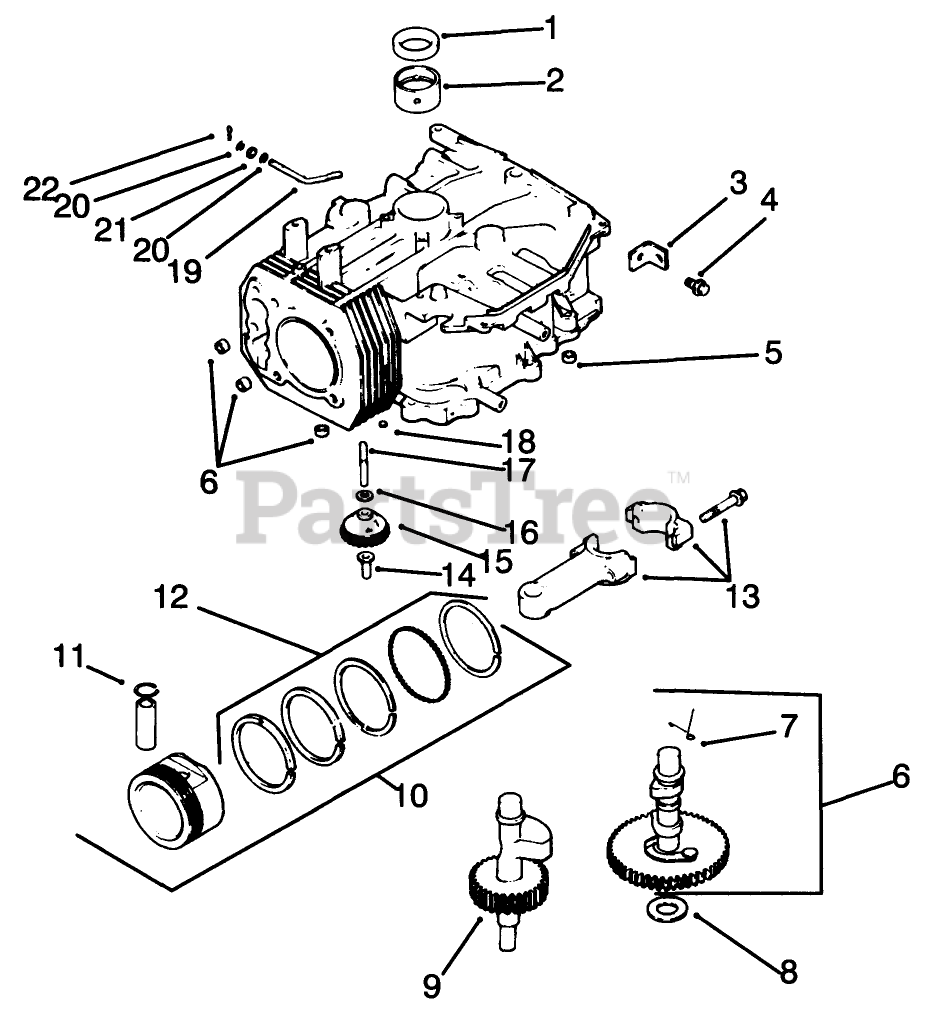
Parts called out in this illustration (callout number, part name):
1	Seal-Crankshaft (Only On: 72042, 72043, 72062, 72063)
2	Bearing-Crankshaft
3	Strap-Lifting (Only On: 72042,72043,72062,72063)
5	Pin-Dowel
6	Camshaft Assembly
7	Spring-Actuating (Only On: 72042,72043,72062,72063)
8	Shim-Camshaft
9	Shaft-Balance
10	Piston W/Ring Set (Std.)
11	Retainer-Piston Pin (Only On: 72042, 72043,72062,72063)
12	Ring Set STD (Only On: 72042,72043,72062,72063)
13	Connecting Rod STD (Only On: 72042, 72063, 72062, 72043)
14	Pin-Governor
15	Gear-Governor ASM (Only On: 72042, 72063, 72062, 72043)
17	Shaft-Govenor Gear
18	Plug-Cap
19	Shaft-Governor Cross (Only On: 72042, 72063, 72062, 72043)
20	Washer-Governor Shaft (Only On: 72042, 72063, 72062, 72043)
21	Seal
22	Pin-Hitch
